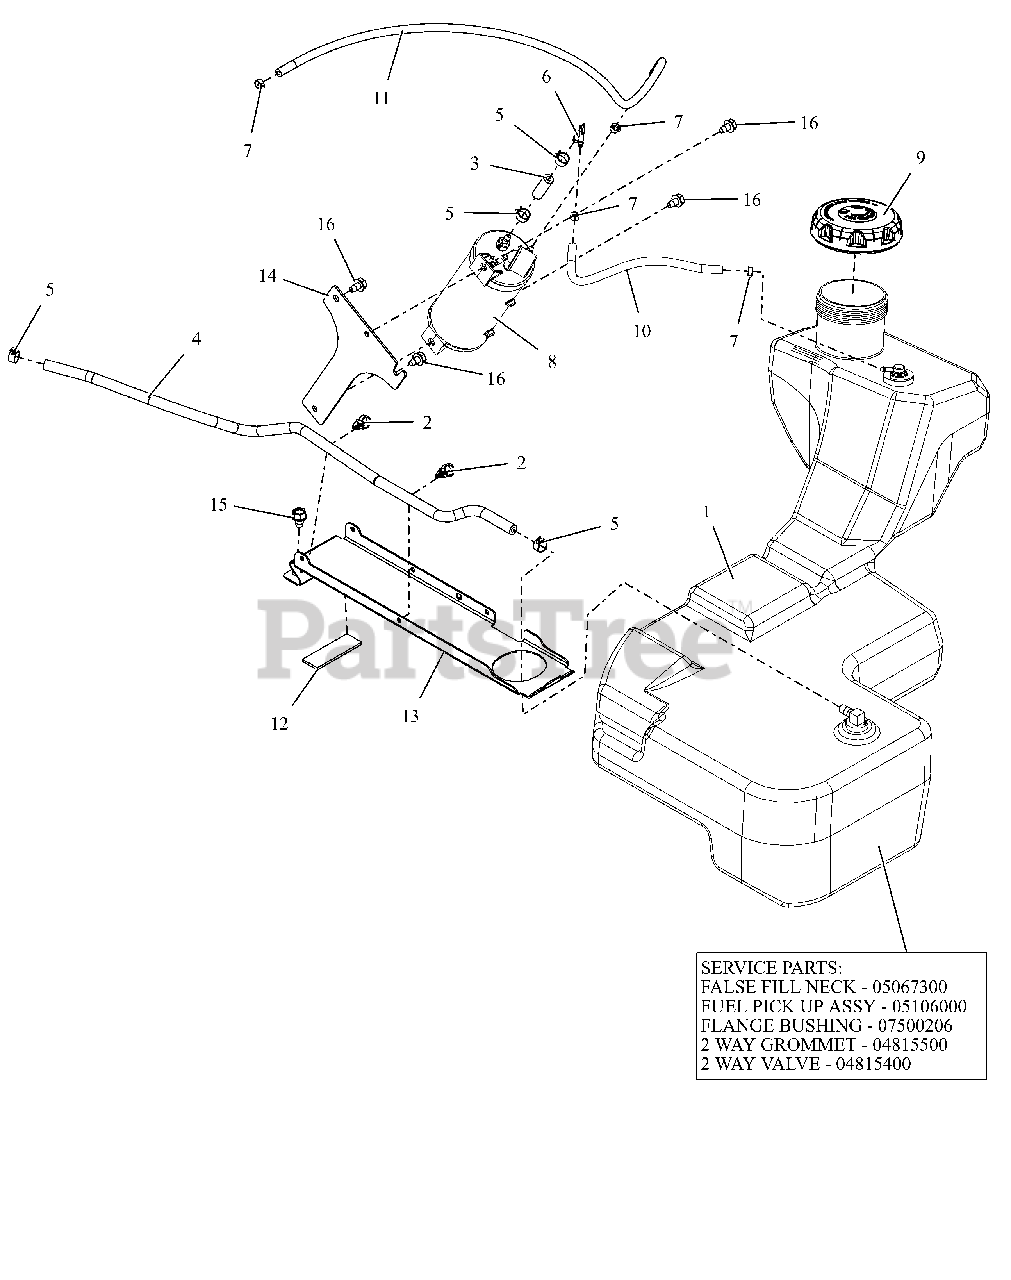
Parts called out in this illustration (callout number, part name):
1	ASM, HD FUEL TANK
2	ROUTING CLIP (1/2" ID)
3	HOSE, .25 LOW-PERM BULK GAS
4	HOSE, .25 LOW-PERM BULK GAS
5	CLAMP, FUEL LINE
6	FITTING-3/16X1/4 90DEGREE VAC
7	CLAMP-HOSE, SPRING .188
8	CANISTER, 400 CC CARB
9	CAP, FUEL VENTIN AUTOLOCK
10	HOSE, .188 30R7 BULK
11	HOSE, .188 30R7 BULK
12	PAD,RBR 1.0"X3.0" W/ADHESIVE
13	BRKT, FUEL TANK HOLD DOWN
14	BRKT, CARB CANISTER MTG (HD)
15	SCR,TAP .375-16X.50 HWH TR ZCC
16	SCR,TAP .312-18X.50 HWH TR ZCC
